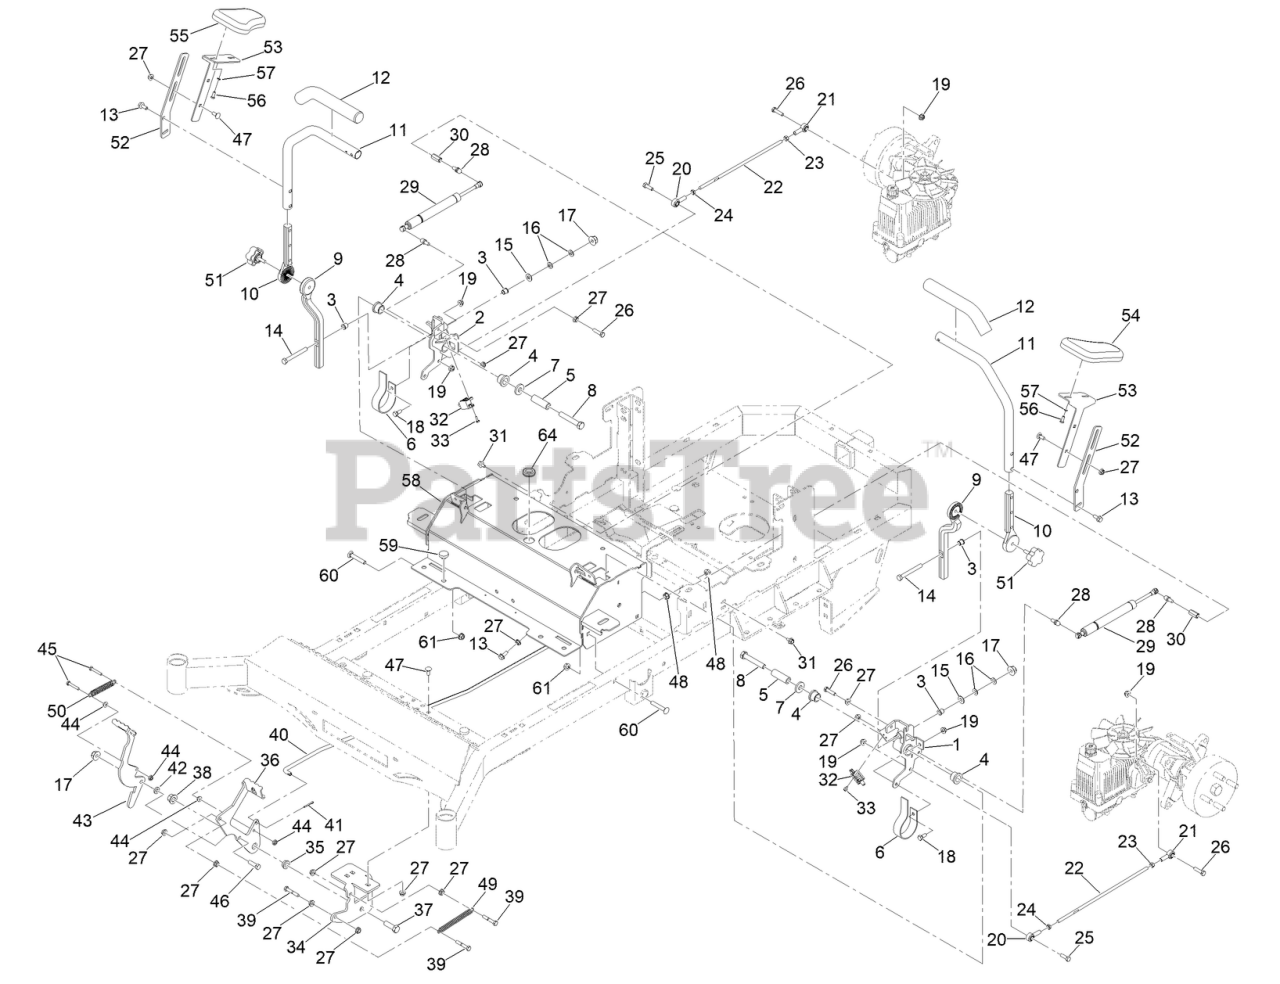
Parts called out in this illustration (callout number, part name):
1	LH PIVOT ASM
2	RH PIVOT ASM
3	BUSHING-FLANGE
4	BUSHING-FLANGE
5	SLEEVE-PIVOT
6	SPRING-LEAF
7	1/2 FENDER WASHER 1-1/4IN OD ZINC
8	1/2-13 X 3 HEX C/S GR 5 ZINC W/LOCTITE
9	ADJUSTABLE LWR DRIVE ARM
10	ADJUSTABLE UPP DRIVE ARM
11	MOWER DRIVE HANDLE TUBE ABC
12	CONTROL ARM HANDLE GRIP
13	SCREW-HHF
14	SCREW-HH
15	WASHER-FLAT
16	WASHER-BELLEVILLE
17	3/8-16 NYLON INSERT FLANGE L/NUT YZ
18	SCREW-HH
19	NUT-HF, NI
20	5/16-24 SPHER ROD END ZINC LH THD FEM
21	5/16-24 SPHER ROD END ZINC RH THD FEM
22	1310 TTQ DRIVE ARM ROD
24	NUT-JAM
25	SCREW-HH
26	SCREW-HH
28	5/16-18X1.286 DAMPER BALL STUD (.562 TL)
29	CONTROL ARM DAMPER
30	STANDOFF-HEX
31	SCREW-HHF
32	NO PLUNGER LIMIT SWITCH
33	8-32 X 1/2 IND. HWH SLOT TYPE F TCS ZINC
34	MWR FRAME BRAKE MTG BRKT PAINT
35	1/2IN ID X 3/4IN OD X 3/8IN FLANGE BUSH
36	MWR BRAKE LOCK LEVER ASSY PAINTED
37	SCREW-HH
38	NUT-LOCK
40	MWR BRAKE LINKAGE
41	PIN-COTTER
42	3/8 ID X 3/4 OD X .125 THK BRONZE WASHER
43	MWR BRAKE UNLOCK LEVER ASSY PAINTED
44	1/4-20 HEX FLANGE NUT
45	1/4-20 X 1-1/4 HEX C/S GR 2 ZINC
46	SCREW-HH
47	BOLT-CARR
48	3/8-16 HEX FLANGE NUT W/SERR ZINC YELLOW
49	2020 MWR BRAKE PEDAL TENSION SPRING
50	MWR BRAKE PEDAL RELEASE SPRING
51	5/16-18 X 1 SL 5-LOBE MALE ST KNOB 1.90
52	MWR ARM PAD TUBE MTG BRKT PAINTED
53	MWR ARM PAD MTG BRKT PAINTED
54	2020 MWR DRIVE ARM SUPPORT PAD LT
55	2020 MWR DRIVE ARM SUPPORT PAD RT
56	SCREW-HSBH
57	1/4 EXT TOOTH LOCKWASHER ZINC
58	ASM, GT-TRAC [GRAY]
59	PUSH-IN RUBBER BUMPER MWR FLOOR
60	SCREW-CARR
64	GROMMET-RUBBER
